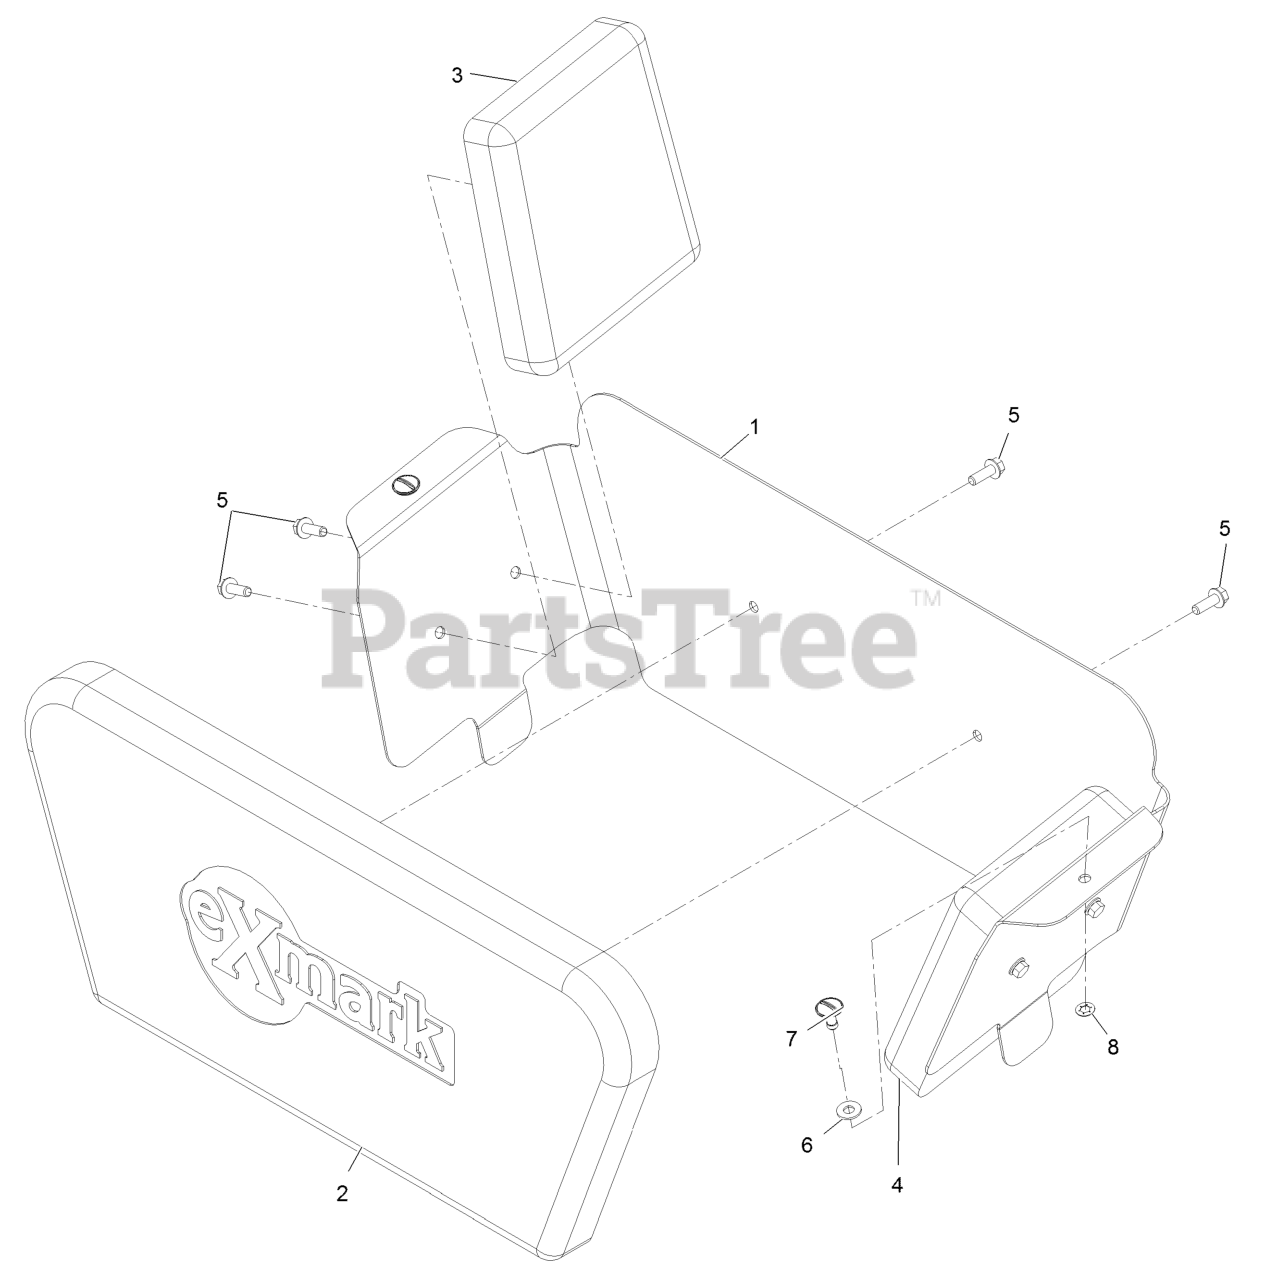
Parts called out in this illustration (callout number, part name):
1	BRACKET-PAD, KNEE
2	PAD-KNEE, CENTER
3	PAD-KNEE, LH SIDE
4	PAD-KNEE, RH SIDE
5	SCREW-HHF
6	WASHER-FLAT
7	STUD-1/4 TURN
8	RETAINER-STUD
